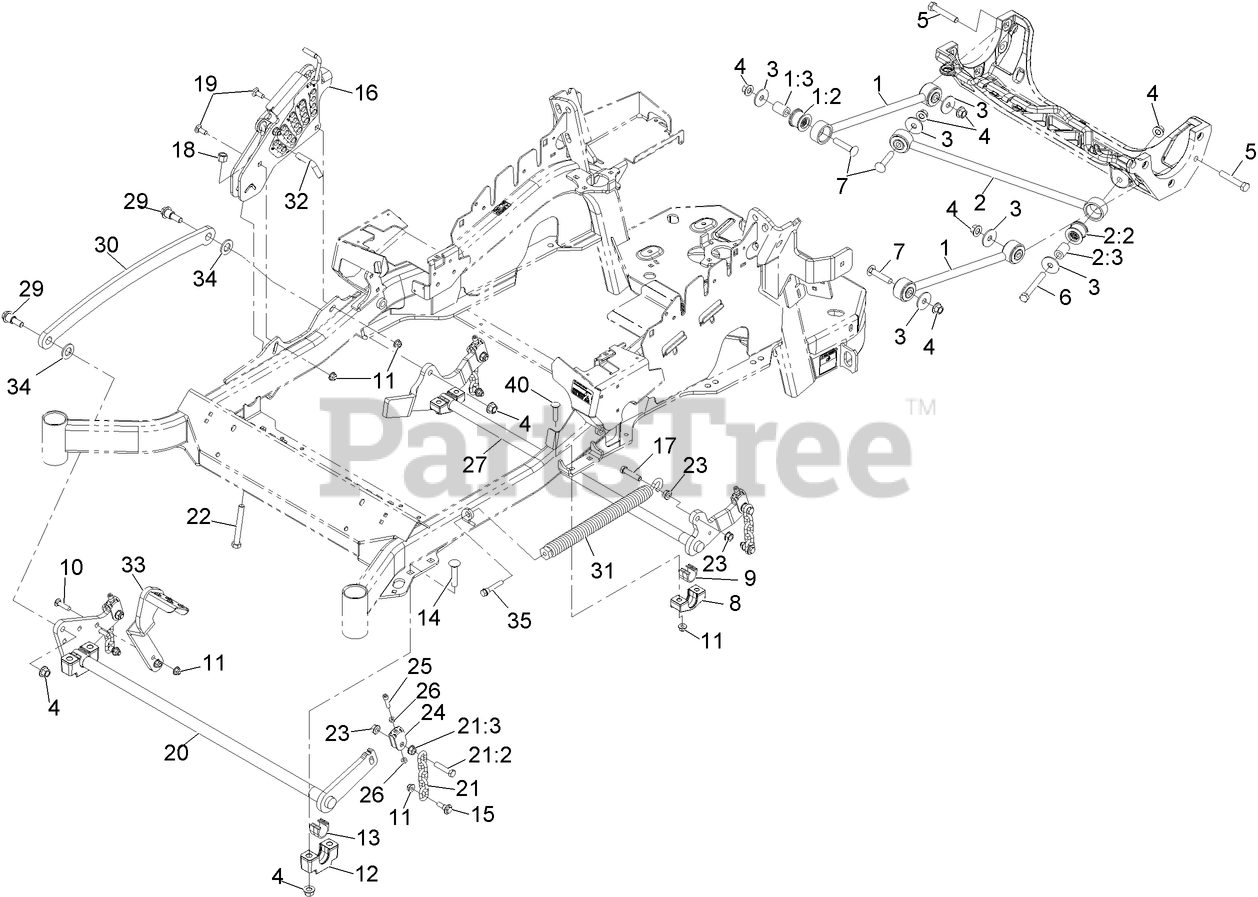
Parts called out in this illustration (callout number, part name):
1	DECK STRUT ASM
1:2	BUSHING-SUSPENSION, RUBBER
1:3	SPACER
2	PANHARD ROD ASM
2:2	BUSHING-SUSPENSION, RUBBER
2:3	SPACER
3	WASHER-THRUST
4	NUT-LOCK
5	SCREW-HH
6	SCREW-HH
7	SCREW-CARR
8	SUPPORT-CROSS SHAFT, REAR BEARING
9	BEARING-CROSS SHAFT, REAR
10	SCREW-CARR
11	NUT-HF, NI
12	SUPPORT-CROSS SHAFT, BEARING
13	BEARING-CROSS SHAFT, FRONT
14	BOLT-CARR
15	SCREW-SHOULDER, HHF
16	HOC ASM
17	SCREW-HH
18	NUT-LOCK, NI
19	BOLT-CARR
20	CROSS SHAFT-FRONT
21	DECK LIFT CHAIN ASM
21:2	SCREW-HH
21:3	NUT-HF
22	BOLT-TAP
23	NUT-HF
24	YOKE-ADJUST, DECK
25	SCREW-HSH
26	NUT-JAM
27	LIFT-DECK, REAR
29	SCREW-SHOULDER, HHF
30	LINK-LIFT, DECK
31	SPRING-EXTENSION
32	PIN-HOC
33	LEVER-FOOT
34	WASHER-FLAT
35	BOLT-SHOULDER
40	SCREW-CARR
